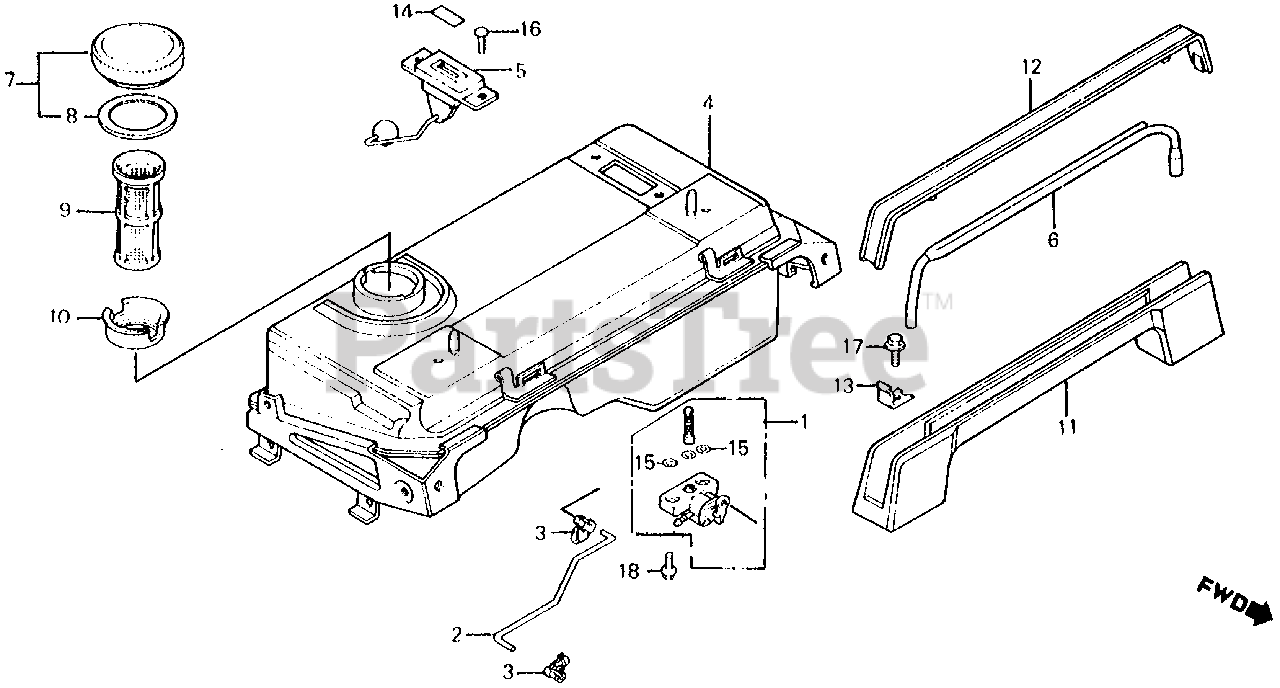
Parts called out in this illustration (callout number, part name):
1	PETCOCK ASSY.
2	ROD, PETCOCK (NOT AVAILABLE)
3	JOINT, ROD
4	TANK, FUEL *R8* (BRIGHT RED)
4	TANK, FUEL *NH44MS* (SPECIAL SILVER METALLIC)
5	METER ASSY., FUEL
6	TUBE, HANDLE BREATHER
7	CAP, FUEL FILLER
8	GASKET, FUEL FILLER CAP
9	FILTER, FUEL
10	HOLDER, FUEL FILTER
11	HANDLE, CARRYING
12	COVER, HANDLE
13	HOOK, HANDLE COVER
14	MARK, FUEL METER
15	GASKET, FIBER (6MM)
16	SCREW, FLAT (5X10)
17	BOLT, FLANGE (6X10)
18	BOLT, FLANGE (6X20)
